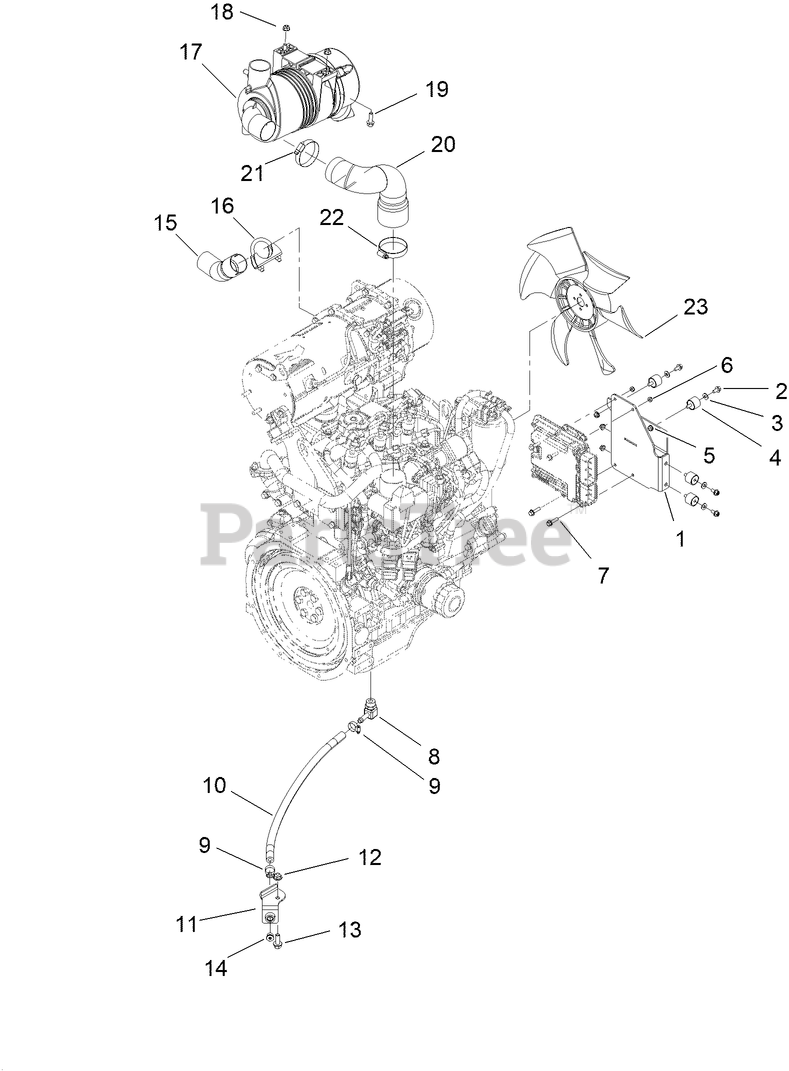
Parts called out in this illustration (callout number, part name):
1	MOUNTING BRACKET
2	SCREW-HHF
3	WASHER-FLAT
4	MOUNT-CYLINDRICAL
5	NUT-HF
6	NUT-HEX, NI
7	SCREW-HHF
8	CONNECTOR
9	CLAMP-HOSE
10	HOSE-HYD
11	OIL PLUG ASM
12	NUT-HF, NI
13	SCREW-HHF
14	PLUG-HEX, HOLLOW
15	TUBE-EXHAUST
16	CLAMP-MUFFLER
17	AIR FILTER (DONALDSON W/ PORT)
18	NUT-HF, NI
19	SCREW-HHF
20	AIR INTAKE HOSE
21	CLAMP-HOSE
22	CLAMP-HOSE
23	FAN - YANMAR 360MM PUSHER
